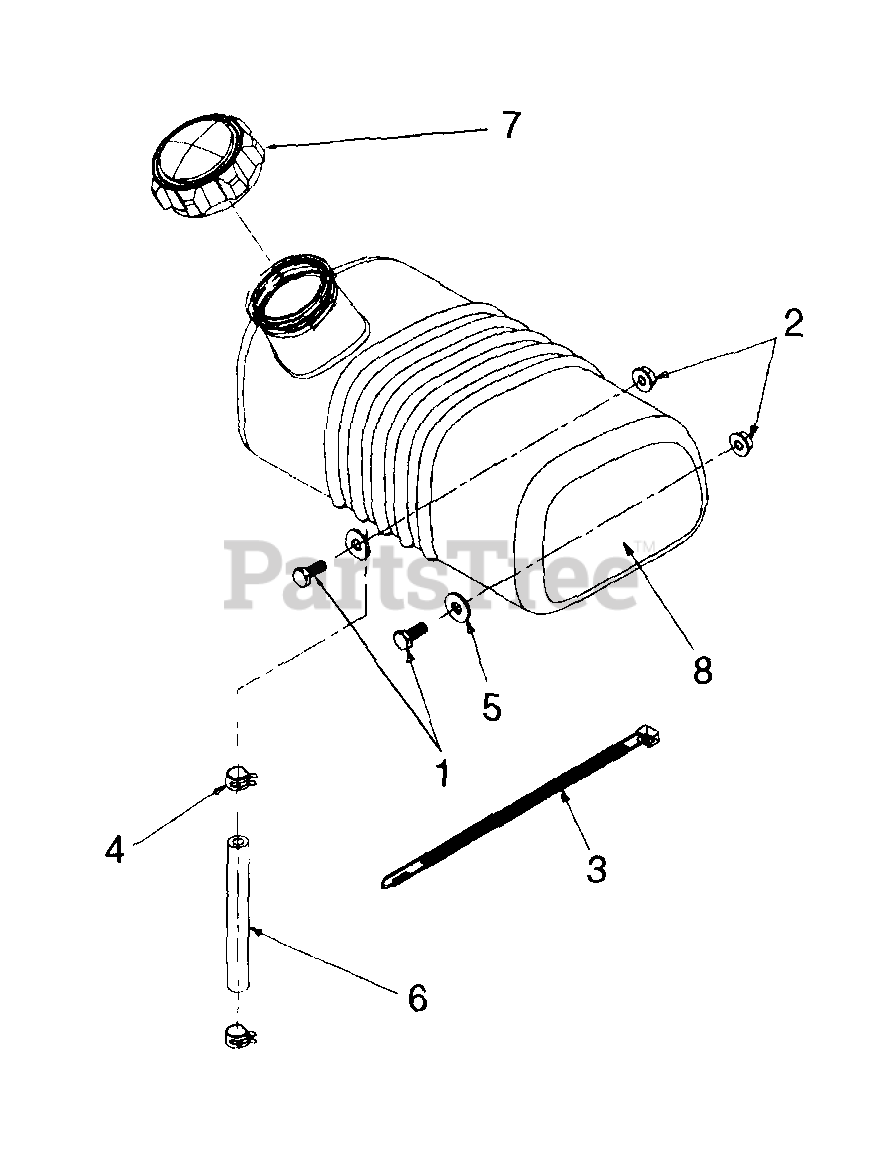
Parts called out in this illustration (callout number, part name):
1	Screw, Hex Cap, 1/4-20 x .625
2	Nut, Hex Flange Lock, 1/4-20
3	Cable Tie, 30.66 Lg
4	Clamp, Hose, 1/2 Inch
5	Washer, Flat, .28 x .74 x .063
6	Hose, Fuel Line 9 Inch
7	Cap, Fuel
8	Tank, Fuel
